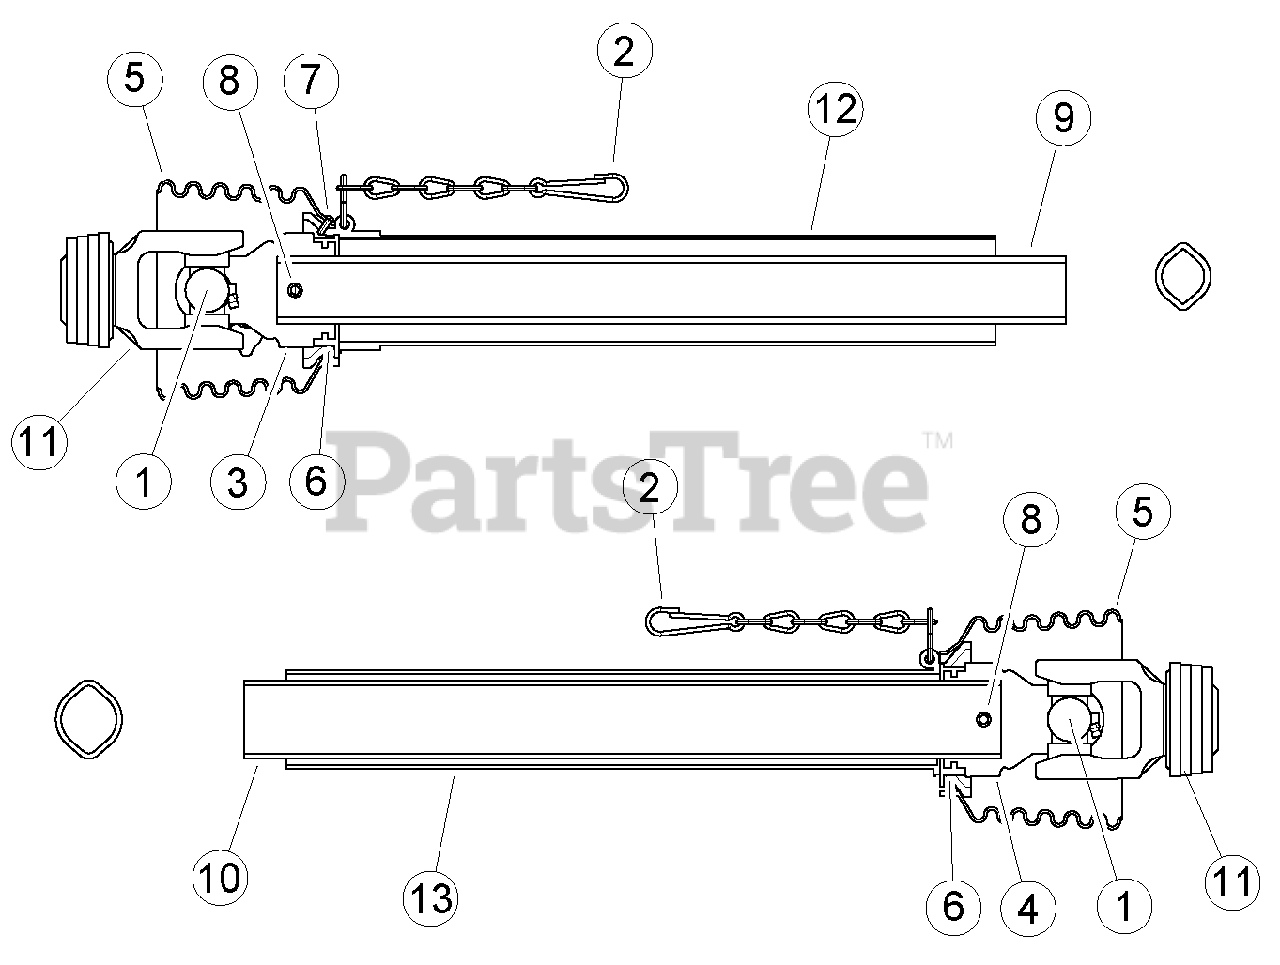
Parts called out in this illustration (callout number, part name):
1	KIT, CROSS & BEARING W-2400
2	CHAIN, SAFETY
3	YOKE, INBOARD 1B
4	YOKE, INBOARD 2A
5	CONE, 6 RIB SAFETY
6	RING, SC25 BEARING
7	SCREW, WS365305
8	PIN, M10 X 80 SPRING
9	PROFILE, INNER 1B
10	PROFILE, OUTER 2A
11	YOKE, 1-3/8-6 SPLINGE ASGE
12	GUARD, TUBE OUTER
13	GUARD, TUBE INNER
